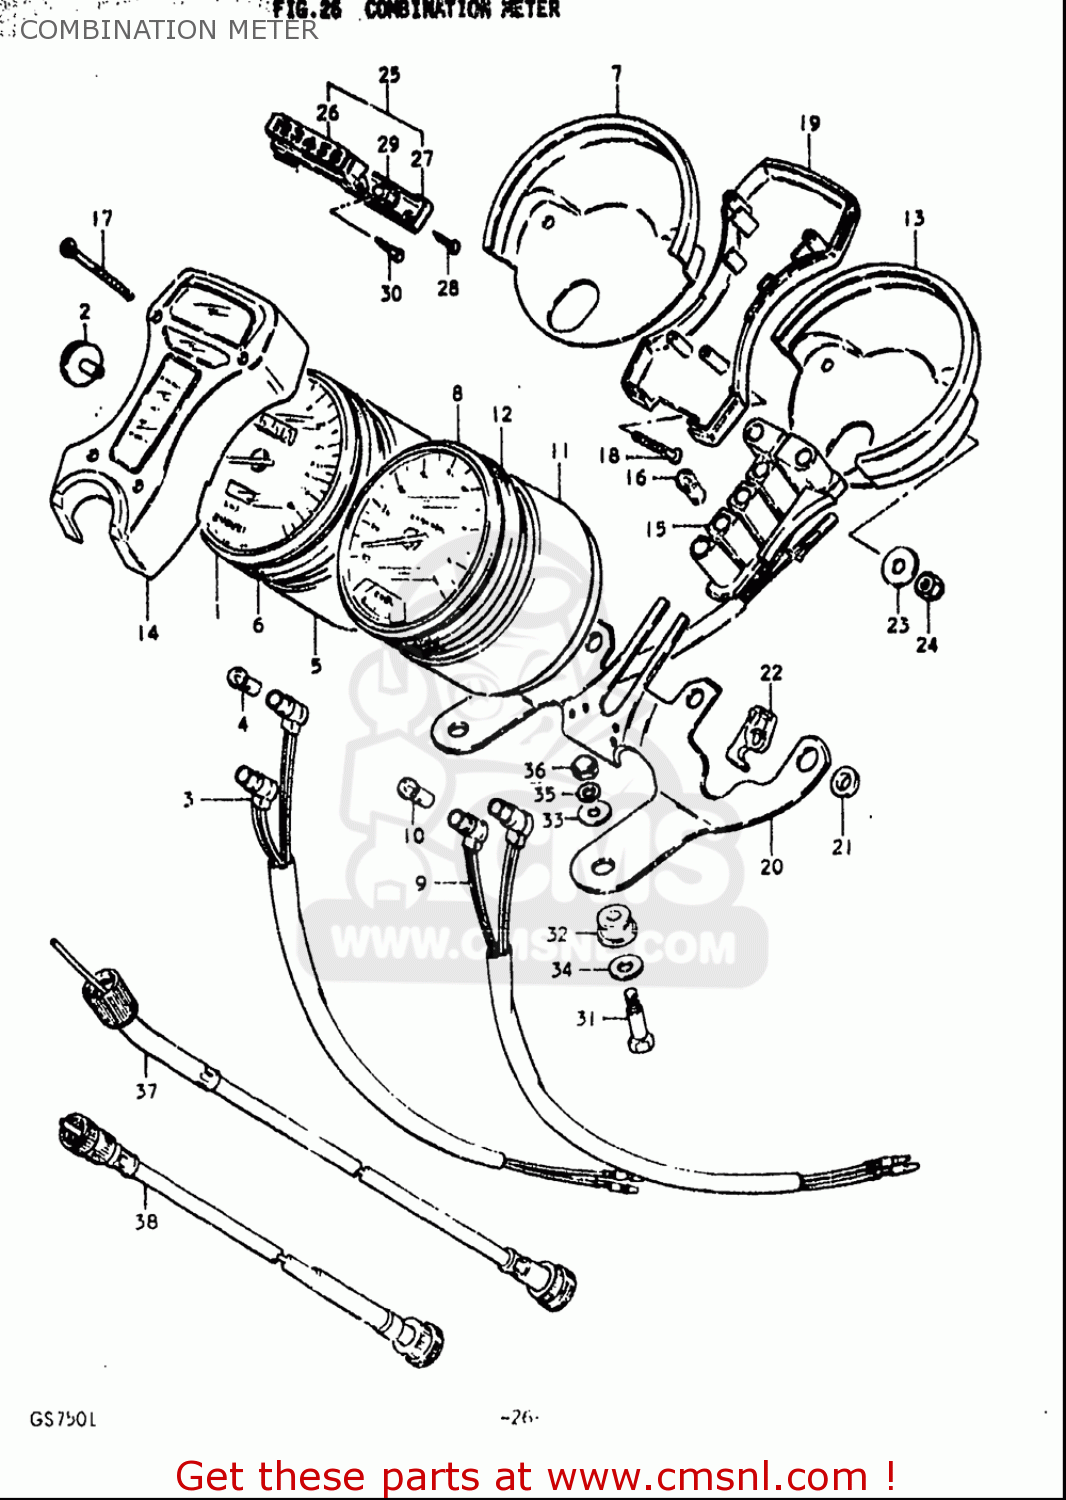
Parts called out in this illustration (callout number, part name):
4	BULB(12V3.4W,STANLEY,A72A)
10	BULB(12V3.4W,STANLEY,A72A)
16	BULB(12V3.4W,STANLEY,A72A)
17	SCREW
18	SCREW
21	CUSHION,METER (A)
23	WASHER(5.5X16X1.2)
24	NUT
27	COVER,LWR
28	SCREW
29	BULB(14V1.12W)
31	BOLT(8X31)
32	CUSHION,METER BRACKET
33	WASHER(8.5X23X1.2)
34	WASHER(10.5X28X1.6)
35	WASHER,LOCK
36	NUT
37	CABLE ASSY,SPEEDOMETER
38	CABLE ASSY,TACHOMETER
